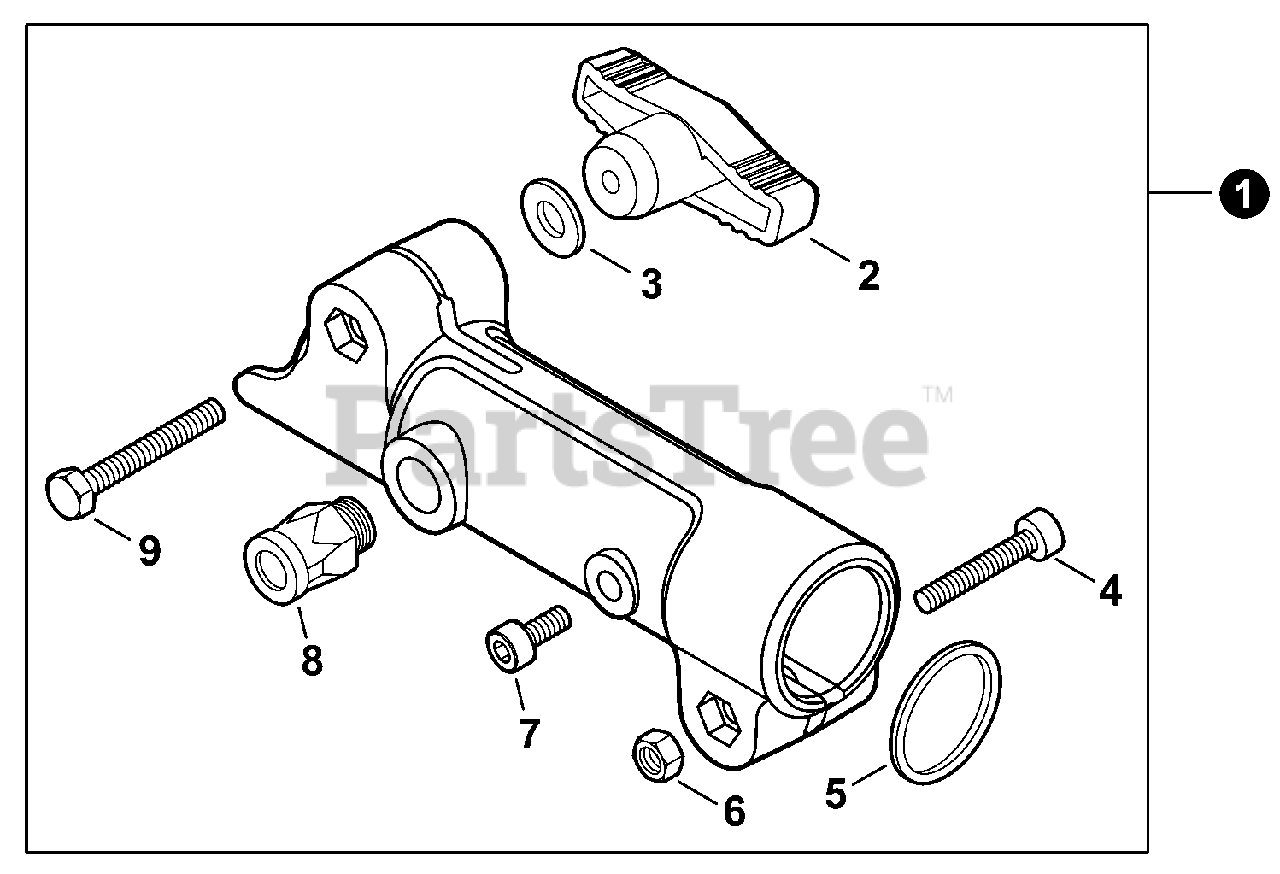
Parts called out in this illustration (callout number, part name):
1	COUPLER ASSY
2	THUMBSCREW
3	WASHER 6.6×20×1.6
4	BOLT, TORX 6×25
5	WASHER 18 SPR STEEL
7	BOLT, TORX 5×10
8	LATCH ASSY
9	BOLT 6×40
